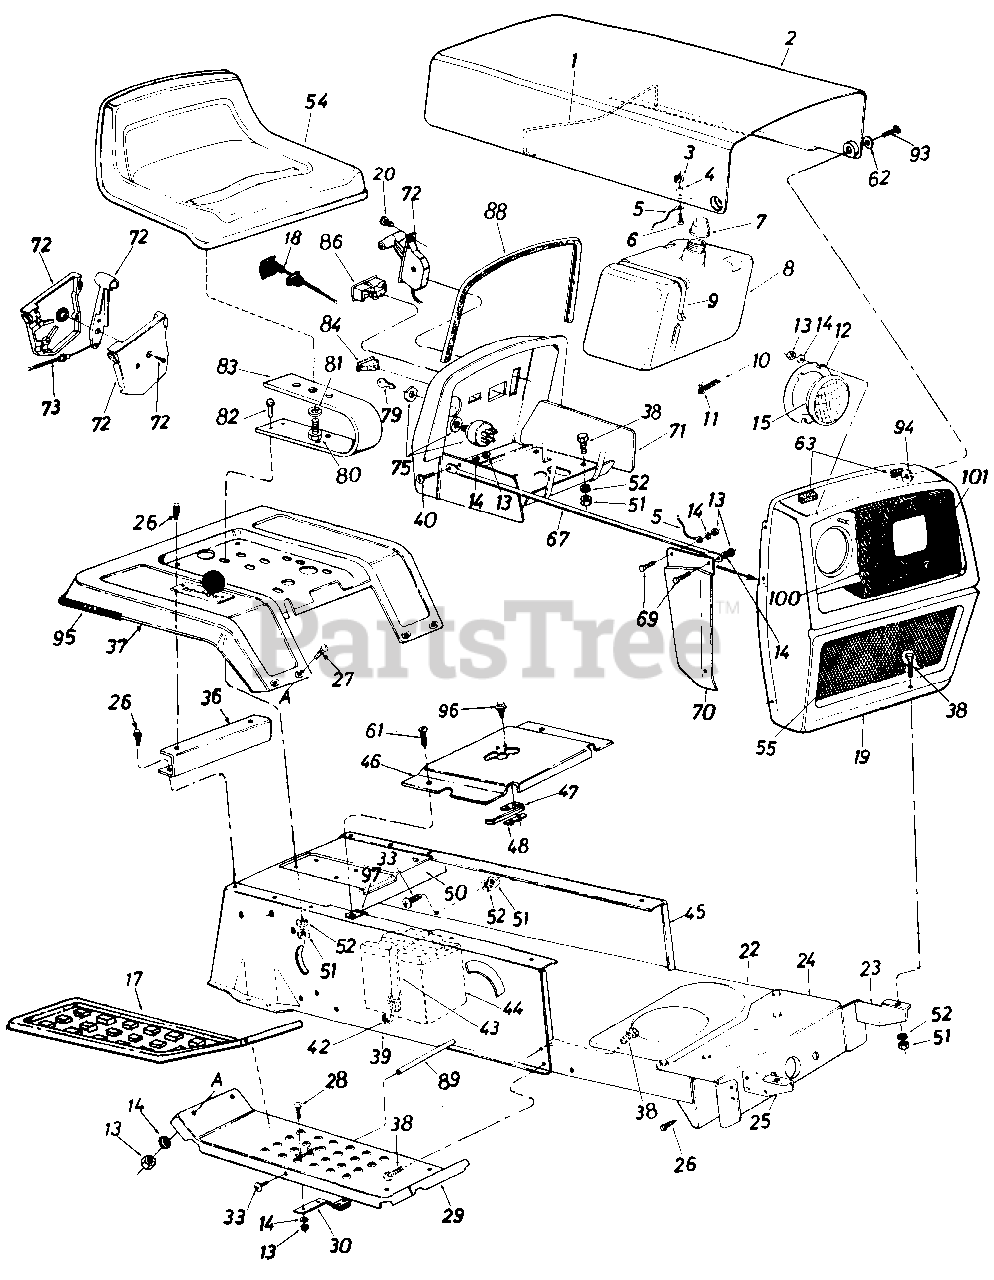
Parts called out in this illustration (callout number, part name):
1	Hood Spring
5	Hood Stop 7" Lg.
6	Truss Hd. Scr. #10-24 x 1/2"*
7	Fuel Cap Gauge
8	Fuel Tank
9	Tie Strap
10	Fuel Line
11	Hose Clamp
12	Headlight Retainer
13	Hex Nut 1/4-20 Thd.
14	L-Wash 1/4" I.D.
15	Headlight
17	Foot Pad
18	Choke Control 29" Lg.
19	Grille Ass'y.
20	Truss Mach. AB-Tap Scr. #10 x .50" Lg.
22	Lower Frame
23	Grille Mount Brkt.-L.H.
24	Front Pivot Brkt.
25	Grille Mount Brkt.-R.H.
26	Hex Wash. Hd. AB-Tap Scr. 5/16 x .75" Lg.
27	Carriage Bolt 1/4-20 x 2.0"*
28	Carriage Bolt 1/4-20 x .62"*
29	Running Board
30	Blade Brake Ass'y.
33	Truss Mach. Scr. 5/16-18 x .75" Lg.*
36	Fender Mount Brace
37	Fender
38	Hex Bolt 5/16-18 x .75" Lg.
39	R.H. Side Frame
40	Hex Bolt 1/4-20 x .62" Lg.
42	Battery Strap Hook
43	Battery Hold Down Strap
44	12-V Battery
45	L.H. Side Frame
46	Shift Cover
47	Reverse Safety Switch
48	Insulator Nut Plate
50	Hitch Plate
51	Hex Nut 5/16-18 Thd.
52	L-Wash. 5/16" I.D.
54	Seat Ass'y.
55	Grille Insert
61	Truss Mach. Tap Scr. #10 x .50" Lg.
62	Washer .39" I.D. x .62" O.D.
63	Foam Strip 3/8 x 1-1/8 x 11/2
67	Grille Support Rod
69	Truss Hd. Scr. 1/4-20 x .75"*
70	R.H. Grille Side Panel
71	Dash Panel Ass'y.
72	Throttle Control Box Ass'y.
73	Throttle Control Wire
75	Ignition Switch
79	Ignition Key
80	Hex Bolt 1/2-13 x 1.0" Lg.
81	L-Wash. 1/2" I.D.
82	Hex Bolt 5/16-18 x 1.0"*
83	Seat Spring 5.5" High
84	Light Switch
86	Ammeter
88	Molding Strip 27" Lg.
89	Running Board Rod
93	Shld. Bolt .375 Dia. x .125
94	Hex L-Nut 1/4-28 Thd.
95	Trim Strip-81"
96	Hex Wash. Hd. AB-Tap Scr. #8 x .50" Lg.
97	Speed Nut #10Z
100	Bezel
101	Truss Scr. #10-24 x .62" Lg.
